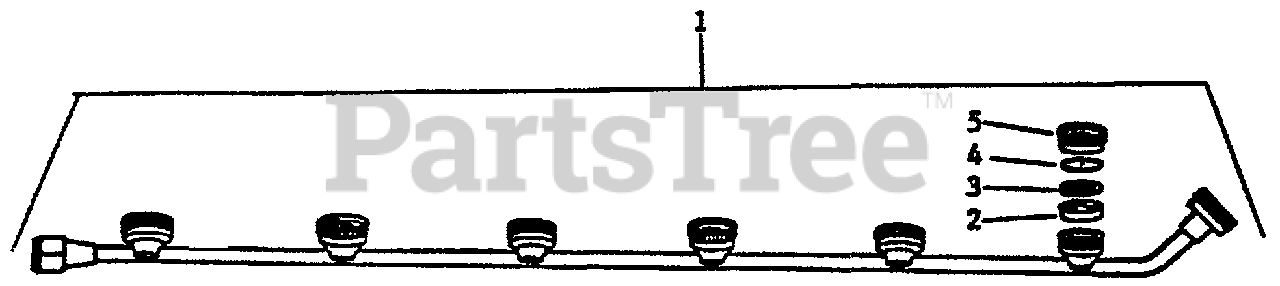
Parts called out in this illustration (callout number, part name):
1	7-HEAD LINE NOZZLE ASSY
3	GASKET, NOZZLE
4	PLATE, NOZZLE
5	CAP, NOZZLE
